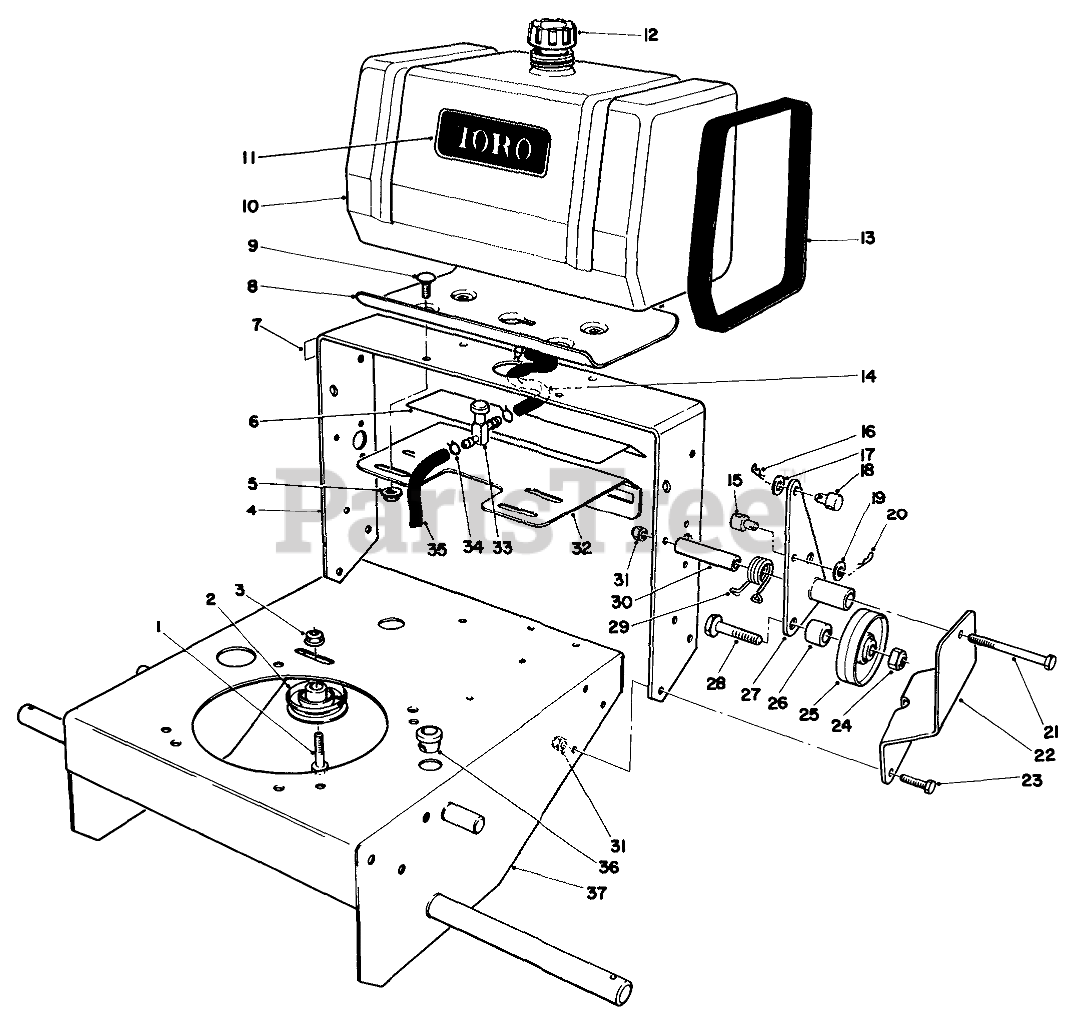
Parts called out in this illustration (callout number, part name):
1	SCREW-HH
2	PULLEY-IDLER
3	NUT-HF
4	Frame-Rear
5	NUT-HF
6	Decal-Ground Speed
7	Decal-Fuel Shut Off
8	Plate-Fuel Tank
9	BOLT-CARR
10	Tank-Fuel
11	GAS TANK DECAL
12	CAP-FUEL ASM
13	Hinge-Seat
14	Hose-Gas
15	ROD FITTING
16	PIN-COTTER
17	WASHER-PLAIN
18	ROD FITTING
19	WASHER-PLAIN
20	PIN-COTTER
21	SCREW-HH
22	Support-Idler L.H.
23	SCREW-HH
24	NUT-LOCK, NI
25	IdlerWheel
26	WHEEL IDLER SPACER
27	LH IDLER BRKT WA
28	SCREW-LEVELER
29	SPRING-TORSION, LH
30	PIVOT-IDLER SPACER
31	NUT-LOCK, NI
32	CONTROL PLATE R
33	FUEL VALVE
34	Clamp
35	HOSE-FUEL
36	GROMMET
37	Frame
